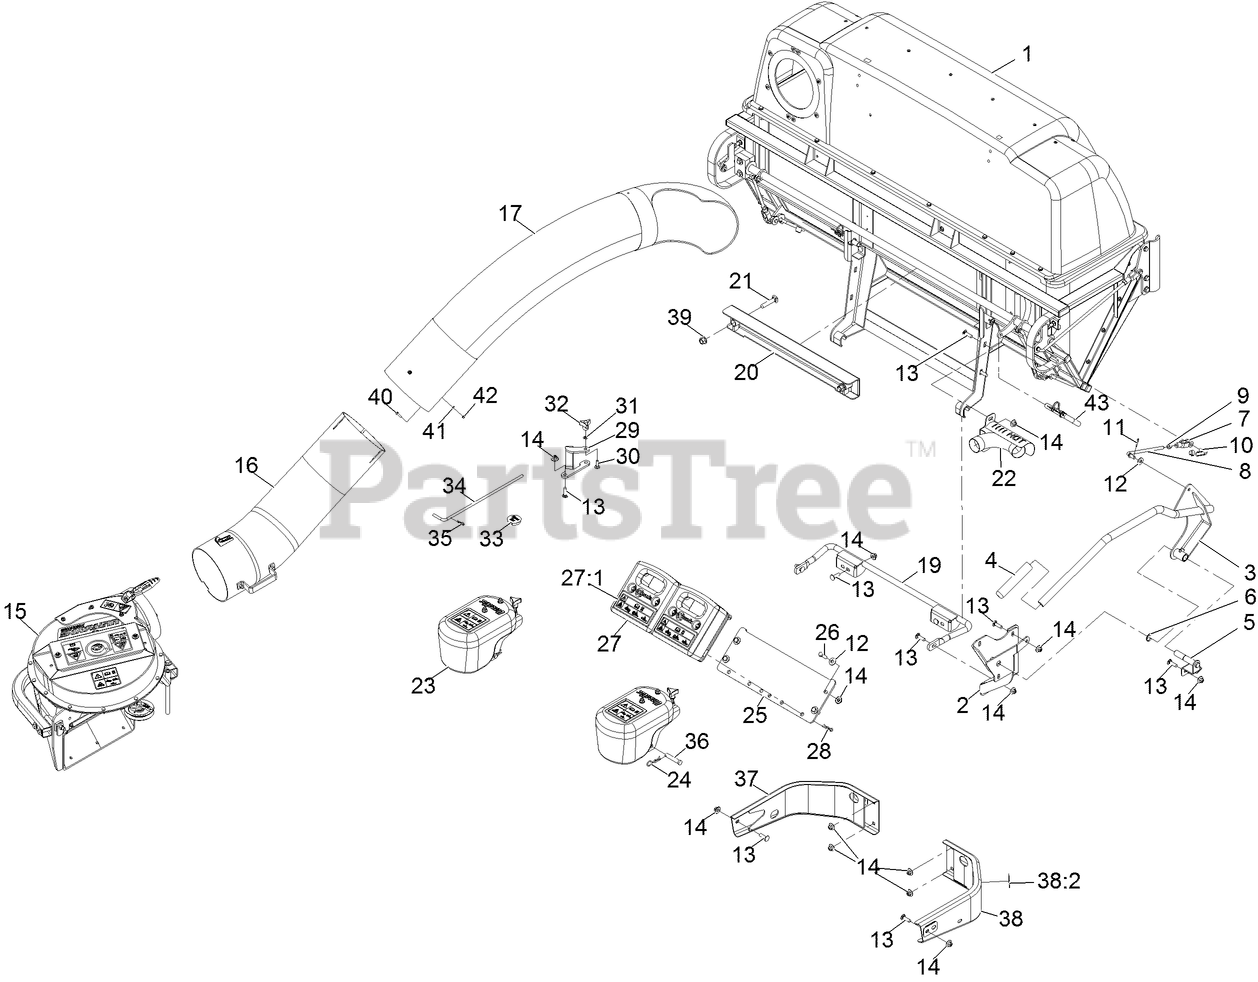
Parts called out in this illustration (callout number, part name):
1	ASM,Hopper Lg Qds
2	MOUNT-PIVOT
3	WLD,DUMP HANDLE
4	HANDLE-GRIP
5	PIN-HANDLE
7	YOKE-LINKAGE, BRAKE
8	LINK-HANDLE
9	NUT-HEX
10	PIN-SPRING, CLEVIS
11	PIN-COTTER
12	WASHER-FLAT
13	Bolt-Carriage 3/8-16 X 1 1/4
14	Nut-Nyloc 3/8-16 Flg
15	ASM, BLOWER LARGE - SVC ONLY
16	LOWER TUBE ASM
17	TUBE-UPPER
19	MOUNT-BAGGER, LOWER
20	MOUNT-BAGGER, UPPER
21	SCREW-CARR
22	EXHAUST DIVERTER ASM
23	ASM,CASTER WEIGHT
24	PIN-COTTER
25	PLATE,WEIGHT ASM MOUNT
26	SCREW-HH
27	ASM,CAST WEIGHT
27:1	DECAL-WARNING WEIGHT
28	PIN-HAIR
29	BRACKET,BELT COVER
30	BOLT-CARR
31	RING-RETAINING, BOLT
32	KNOB-3 PRONG
33	PLUG, BLACK NYLON 1.75
34	PIN,CHUTE PIVOT
35	PIN-COTTER
36	PIN-CLEVIS
37	BUMPER-RH
38	LH BUMPER ASM
38:2	DECAL-WARNING
39	Nut-Lock 1/2-13
40	SCREW-HWH
41	WASHER-FLAT
42	NUT-LOCK, NI
43	PIN-MOUNT, BAGGER
